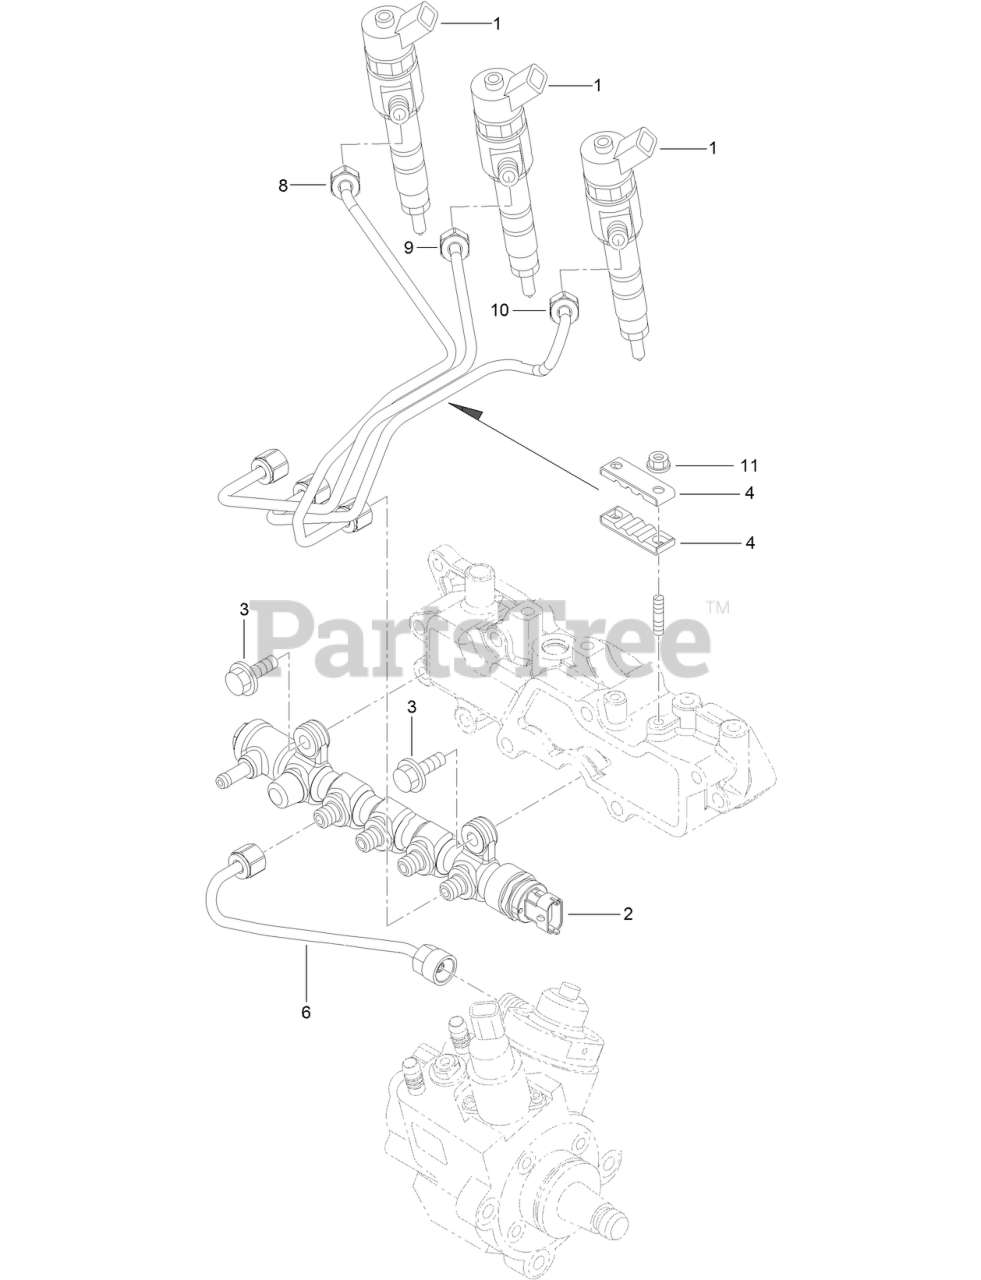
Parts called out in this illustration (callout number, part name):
1	INJECTOR ASM
2	RAIL ASM
4	RETAINER
6	RAIL IN PIPE ASM
8	INJECTION PIPE ASM
9	INJECTION PIPE ASM
10	INJECTION PIPE ASM
